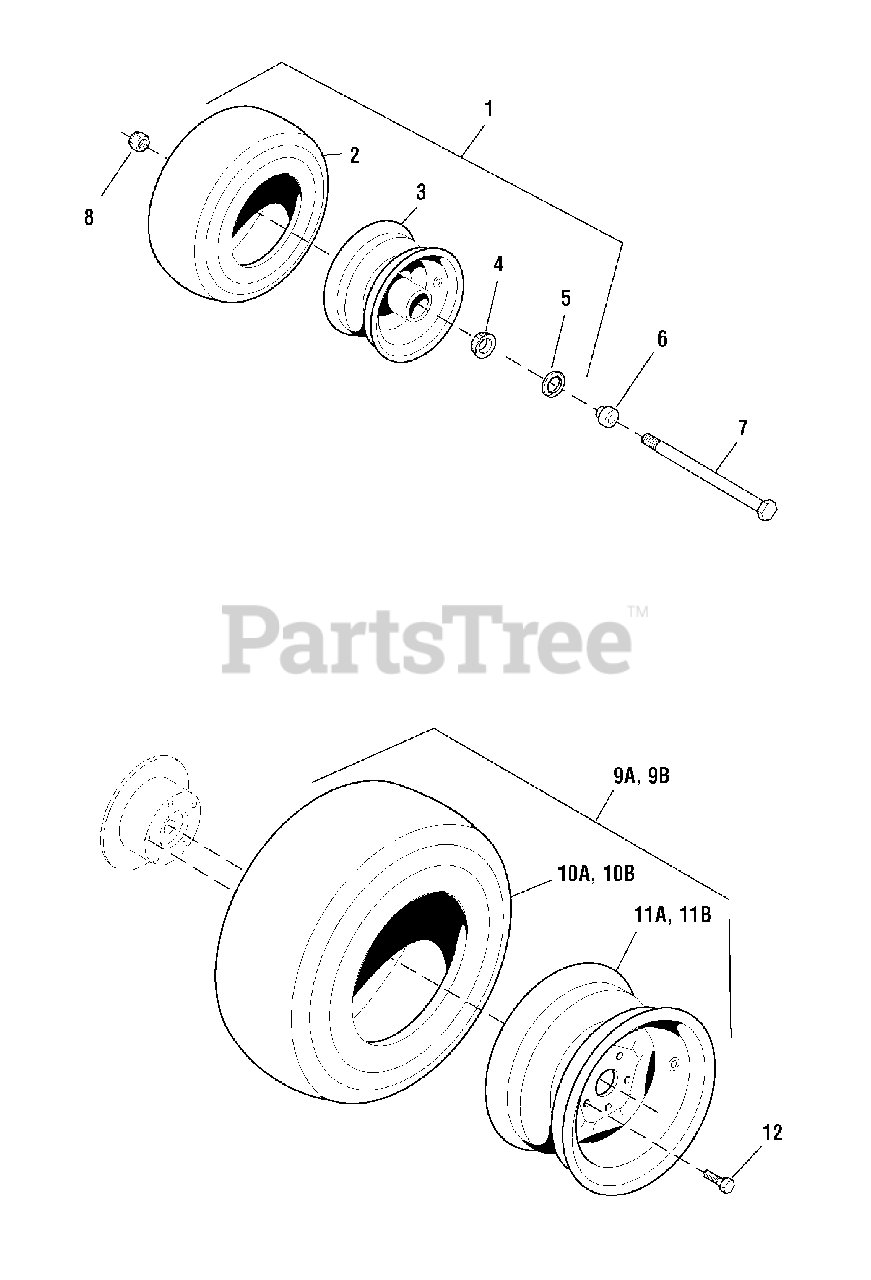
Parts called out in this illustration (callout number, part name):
1	WHEEL & TIRE ASSEMBLY, Front, 13 x 5.0 x 6, Complete
2	TIRE, Front, 13 x 5.0 x 6
3	WHEEL ASSEMBLY, Front, for 13 x 5.0 x 6 Tires, Complete
4	BEARING, TAPERED CONE
5	SEAL, GREASE
6	ADAPTER, Caster Wheel (2 per tire)
7	CAPSCREW, Hex Hd, 1-2/13 x 7-1/2
8	NUT, Hex, Nylon Lock, 1-2/13
9A	WHEEL & TIRE ASSEMBLY, Rear, 23 x 10.5 x 12, Complete (Includes Ref 10A & 11A)(ZT2561F - S/N: 877 & below)(ZT2761F - S/N: 937 & below)
9B	WHEEL & TIRE ASSEMBLY, Rear, 23 x 10.5 x 12, Complete (Includes Ref 10A & 11A)(ZT2561F - S/N: 878 & above)(ZT2761F - S/N: 938 & above)
10A	TIRE, Rear, 23 x 10.5 x 12 (ZT2561F - S/N: 877 & below)(ZT2761F - S/N: 937 & below)
10B	TIRE, Rear, 23 x 10.5 x 12 (ZT2561F - S/N: 878 & above)(ZT2761F - S/N: 938 & above)
11A	WHEEL ASSEMBLY, Rear, 12 x 8.5 (ZT2561F - S/N: 877 & below)(ZT2761F - S/N: 937 & below)
11B	WHEEL ASSEMBLY, Rear, 21 x 8.5 (ZT2561F - S/N: 878 & above)(ZT2761F - S/N: 938 & above)
12	WHEEL LUG, 1/2 x 1-5/8
